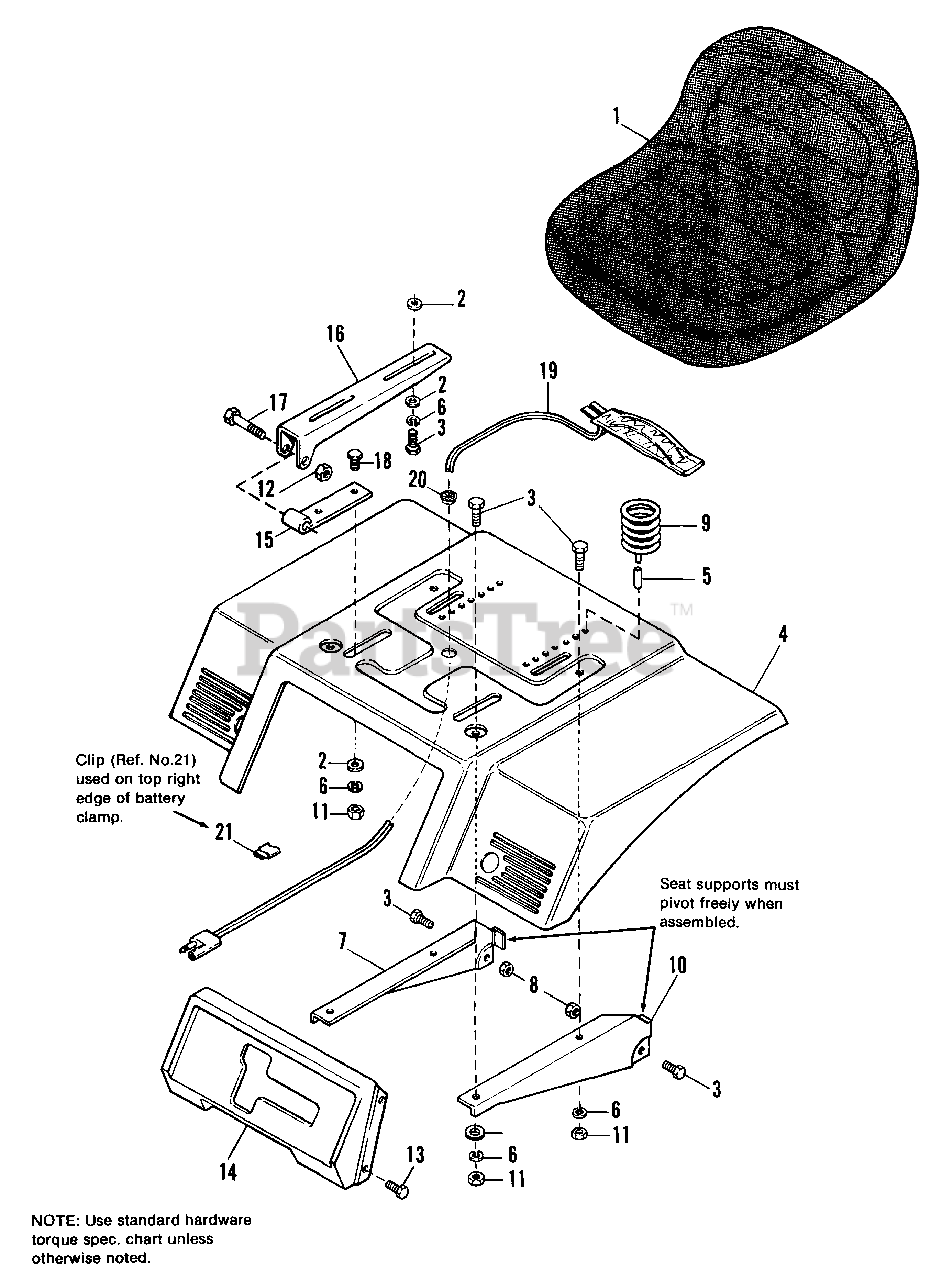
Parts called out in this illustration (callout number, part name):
2	WASHER, Plain, 5/8
3	CAPSCREW, Hex, 5/16-18 x 3/4
4	DECK, Seat
5	COVER, Wire
6	LOCKWASHER, 5/16
7	SUPPORT, Seat, R.H.
8	LOCKNUT, Hex, 5/16-18
9	SPRING, Seat
10	SUPPORT, Seat, L.H.
11	NUT, Hex, Full, 5/17-18
12	LOCKNUT, Hex, 3/8-16
13	SCREW, Taptite, 1/4-20 x 1/2
14	PANEL, Shift
15	HINGE, Lower
16	HINGE, Upper
17	CAPSCREW, Hex, 3/8-16 x 2
18	CAPSCREW, Hex, 5/16-18 x 1.0
19	SWITCH, Seat
20	BUSHING, Universal
